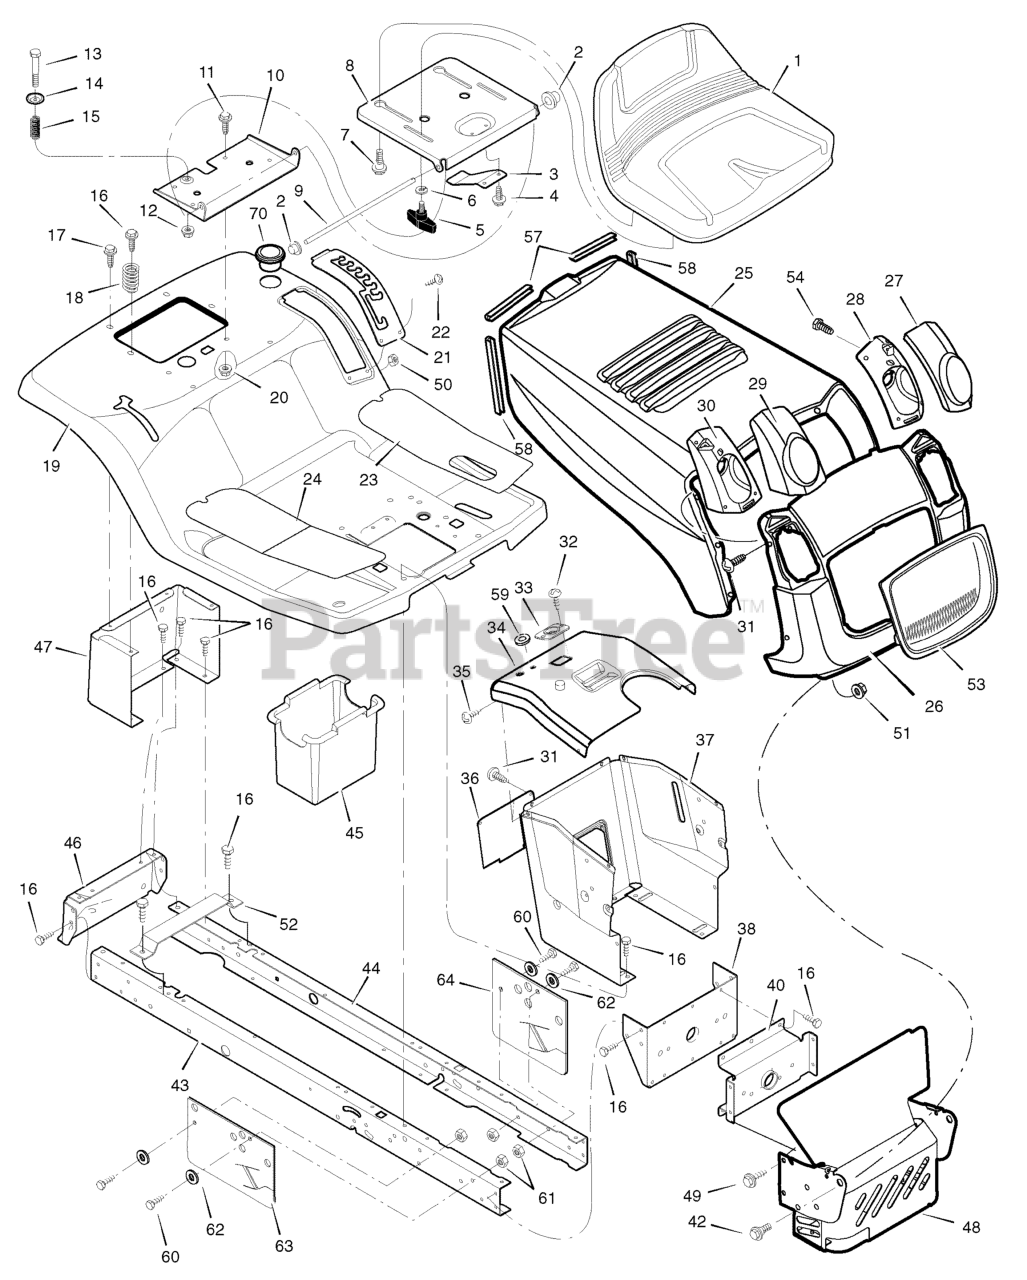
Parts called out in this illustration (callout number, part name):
2	CAP, Push On
5	BOLT, Wing
6	WASHER
7	BOLT, Shoulder
8	SUPPORT, Seat
9	ROD, Pivot
10	BRACKET, Seat Pivot
11	BOLT
13	BOLT, Shoulder
14	WASHER, Cup
19	DECK, Seat
20	NUT
21	PLATE, Lift
23	MAT, Left
24	MAT, Right
26	GRILLE, X1/X3
27	LENS, Left
28	HOUSING. Left Headlamp
29	LENS, Right
30	Housing, Right Headlamp
33	BEARING, Steering
36	PANEL, Access
37	SUPPORT, Dash
38	BRACKET, Rear Hanger
40	AXLE, Hanger
42	BOLT, Shoulder
43	FRAME, Right
44	FRAME, Left
45	Container, Battery
46	PLATE, Hitch
47	PANEL, Rear
48	SHIELD, Heat
51	NUT
52	SUPPORT, Battery
53	INSERT, Grille
54	SCREW, Hex Head
55	FASTENER, Panel
57	TRIM, Hood (3.75")
58	TRIM, Hood (6.5")
59	GROMMET, Parking Brake
60	CAPSCREW, Hex Head, 5/16-18 x 1
61	NUT, Hexlock
63	GUARD, Rubber, RH, Black
64	GUARD, Rubber, LH, Black
70	HOLDER, Cup
